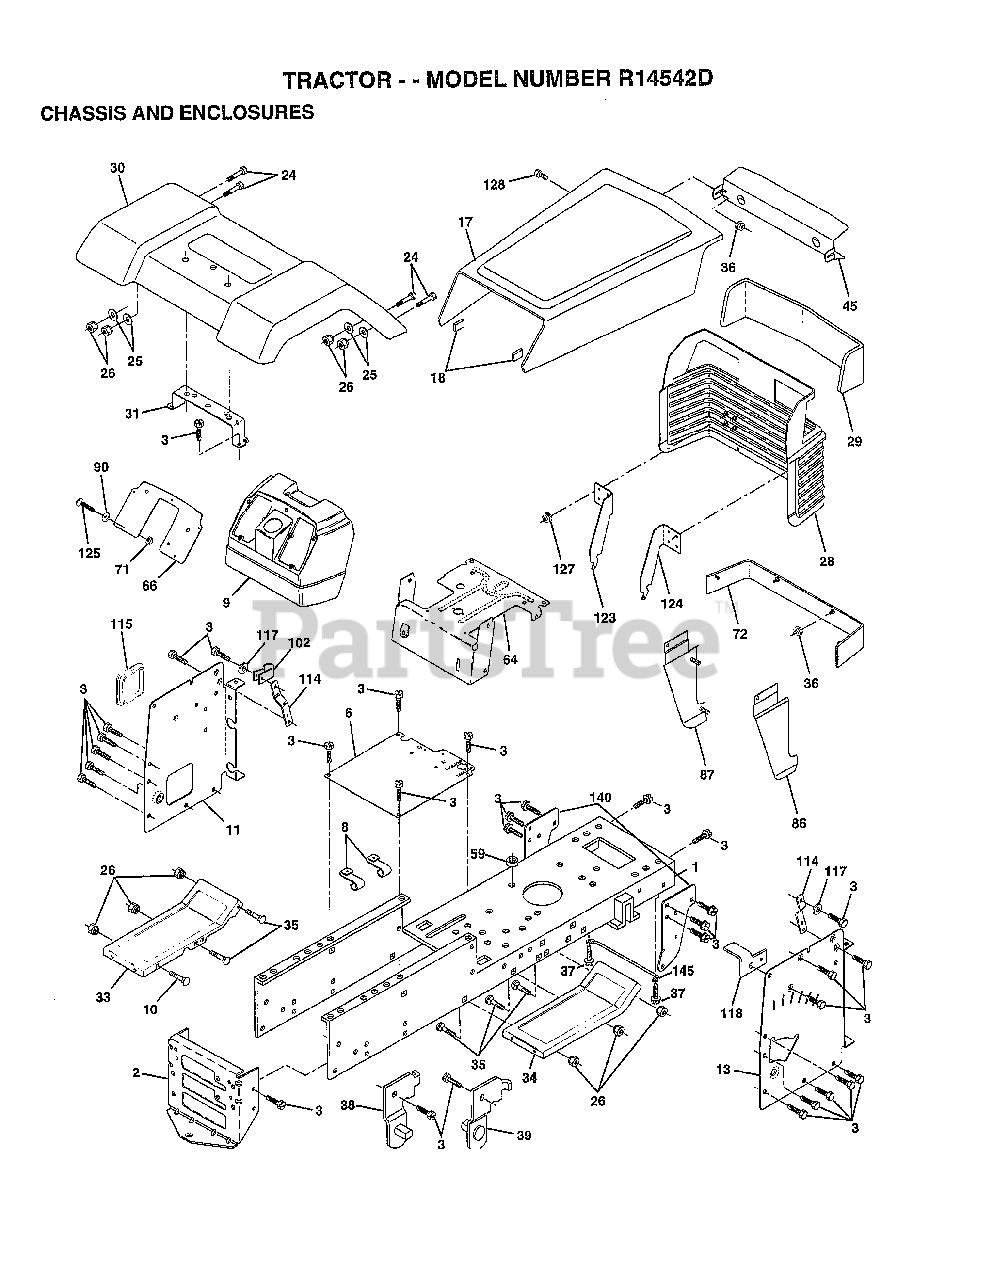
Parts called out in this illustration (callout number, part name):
3	SCREW
6	SADDLE-SILKSCREEN
8	"CLIP,INSULATOR"
9	DASH.PLASTIC.BLK
11	PANEL.DASH.LH.
13	PANEL.DASH.RH.NOT
17	HOOD.ASM.YTGT.PNT
24	BOLT
25	WASHER
26	NUT
28	GRILLE ASM WELD
30	FENDER BRACKET
31	BRKT FENDER
33	FOOTREST LH
34	FOOTREST RH
35	BOLT
36	PAL NUT LT
38	BRACKET ASM LH
39	BRACKET ASM RH
64	DASH.LOWER.LT
66	PLATE SLKSCR.OM
71	NUT HXKEP 1/4X20
72	STRAP GRILLE 505
86	PANEL.SIDE.RH.ASM
87	PANEL.SIDE.LH.ASN
90	WASHER PM
102	CLIP T
114	BRACKET.SUPT.DASH
115	COVER ACCESS
117	WASHER.SERRATED.
118	BRACKET.CLUTCH.MC
123	BRACKET.PICK.LH.
124	BRACKET.PICK.RH.
125	SCREW
127	PAL NUT
128	SCREW SPECIAL
140	BRKT SUSPENSION
145	"ROD POVOT,CHASSIS"
